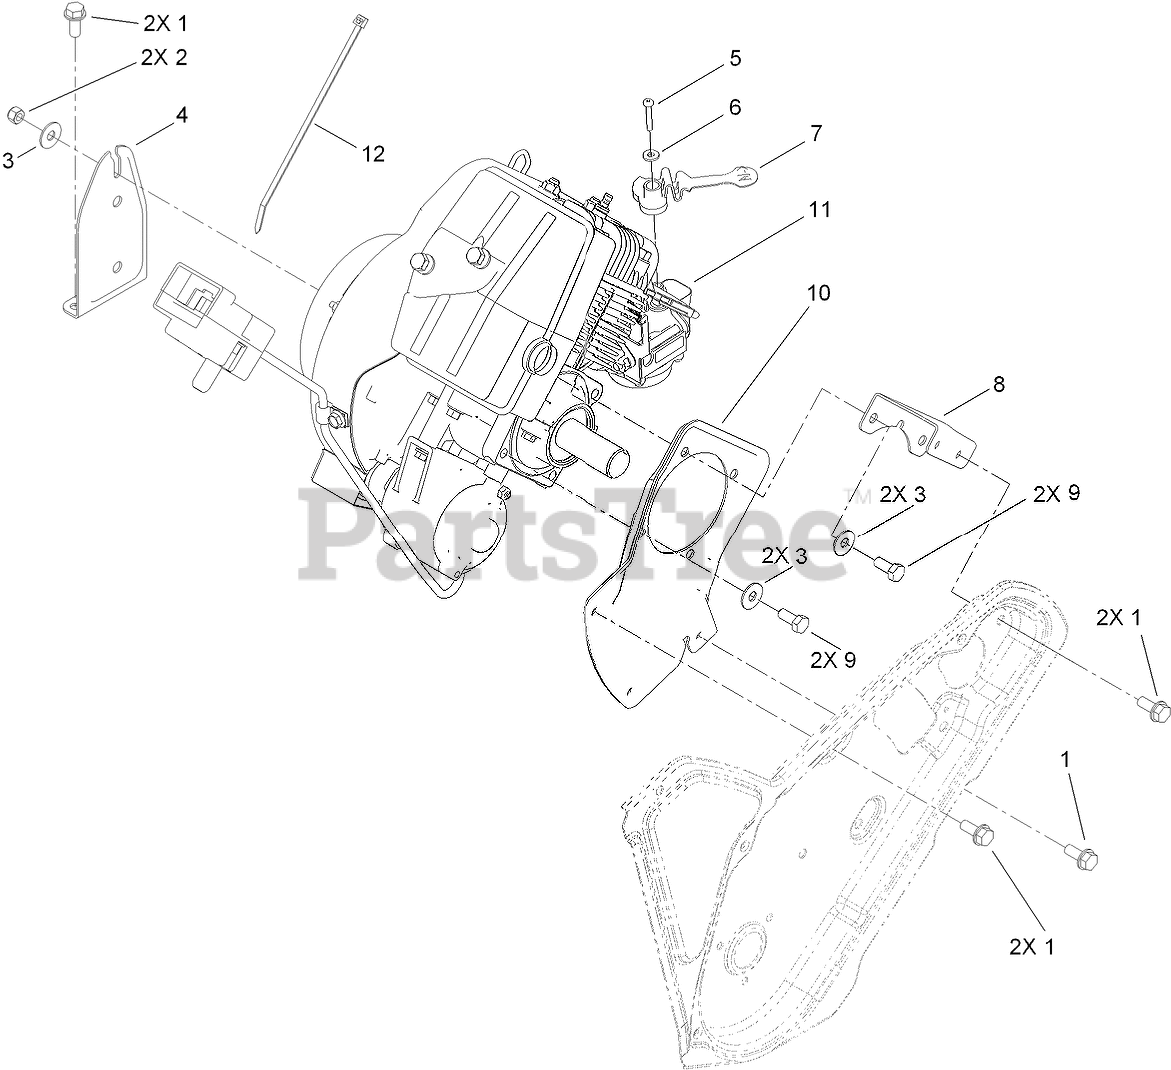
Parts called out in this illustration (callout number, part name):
1	SCREW-HWHTF
2	NUT-LOCK, NI
3	WASHER-BELLEVILLE
4	BRACKET-RECOIL
5	SCREW-PPH, PLASTITE
6	WASHER-FLAT
7	LEVER-CHOKE
8	SUPPORT-ENGINE, SIDE
9	SCREW-HH
10	PLATE-ENGINE, PTO
12	TIE-CABLE
